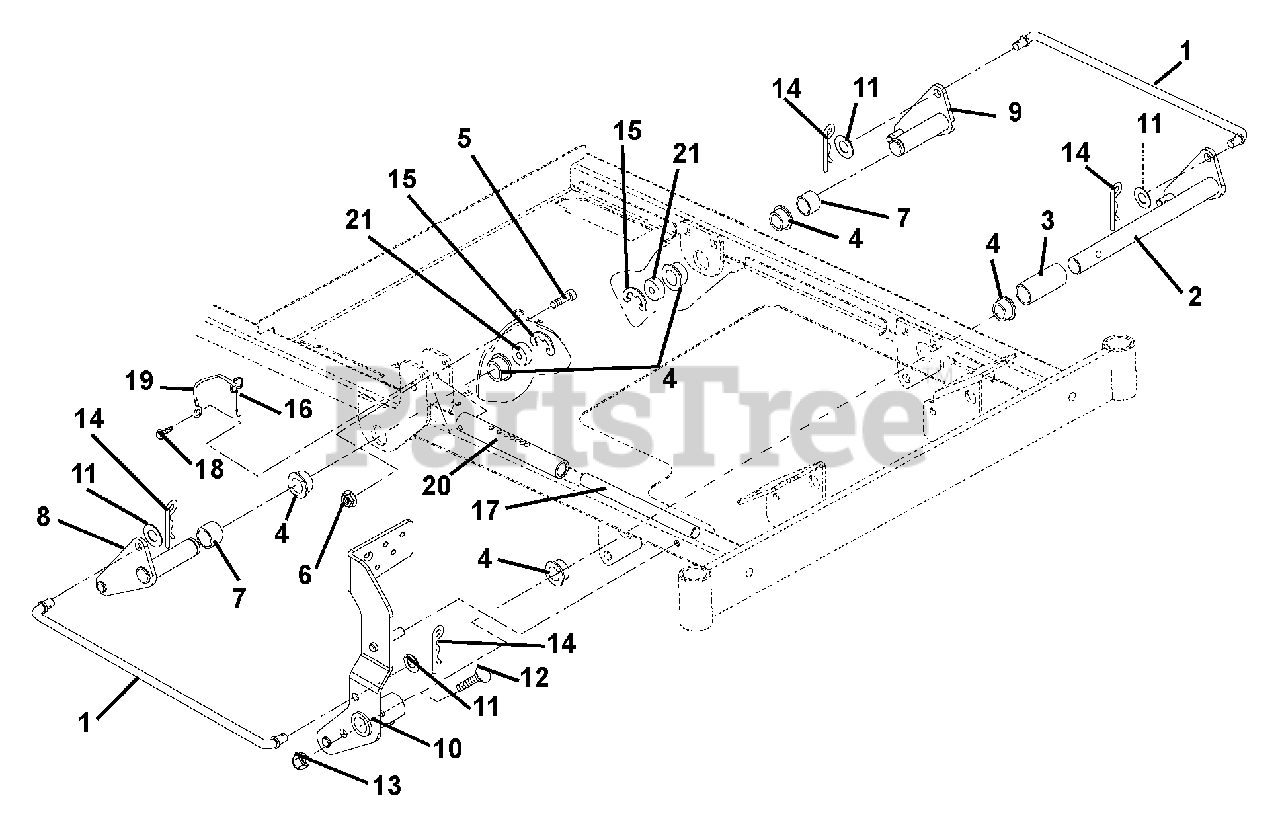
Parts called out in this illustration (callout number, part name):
1	ROD, LIFT
2	WELDMENT,FRONT LIFT
3	BSHG, SPCR 1.01X1.25X2.63 PM
4	BSHG-FLG 1.000X1.12X.62X1.50BR
5	@BLT-HEX .38-16X2.75 GR5 YWZC
6	@NUT-LK-NYL-FLG .38-16 YWZC
7	BSHG-SPCR 1.032X1.250X.88 PM
8	WELDMENT, LIFT, REAR - RH
9	WELDMENT, LIFT, REAR - LH
10	WMT, FOOT PEDAL
11	@WSHR-FL-STL.531X1.06X.095YWZC
12	@BLT-HEX .38-16X2.00 GR5 YWZC
13	@NUT-LK-NYL-FLG .38-16 YWZC
14	PIN, HAIR, EXT - #16 YWZC
15	RG-RTNG .822X1.500X.050 TYP E
16	PIN, SPRING BALL .375OD X 1.50
17	ROD, LIFT
18	@SCR-TAP .25-20X.37 HWH YWZ TR
19	CBL,HOOD
20	TUBE, LIFT STOP
21	BSHG, SPCR 1.032X1.25X.25 PM
